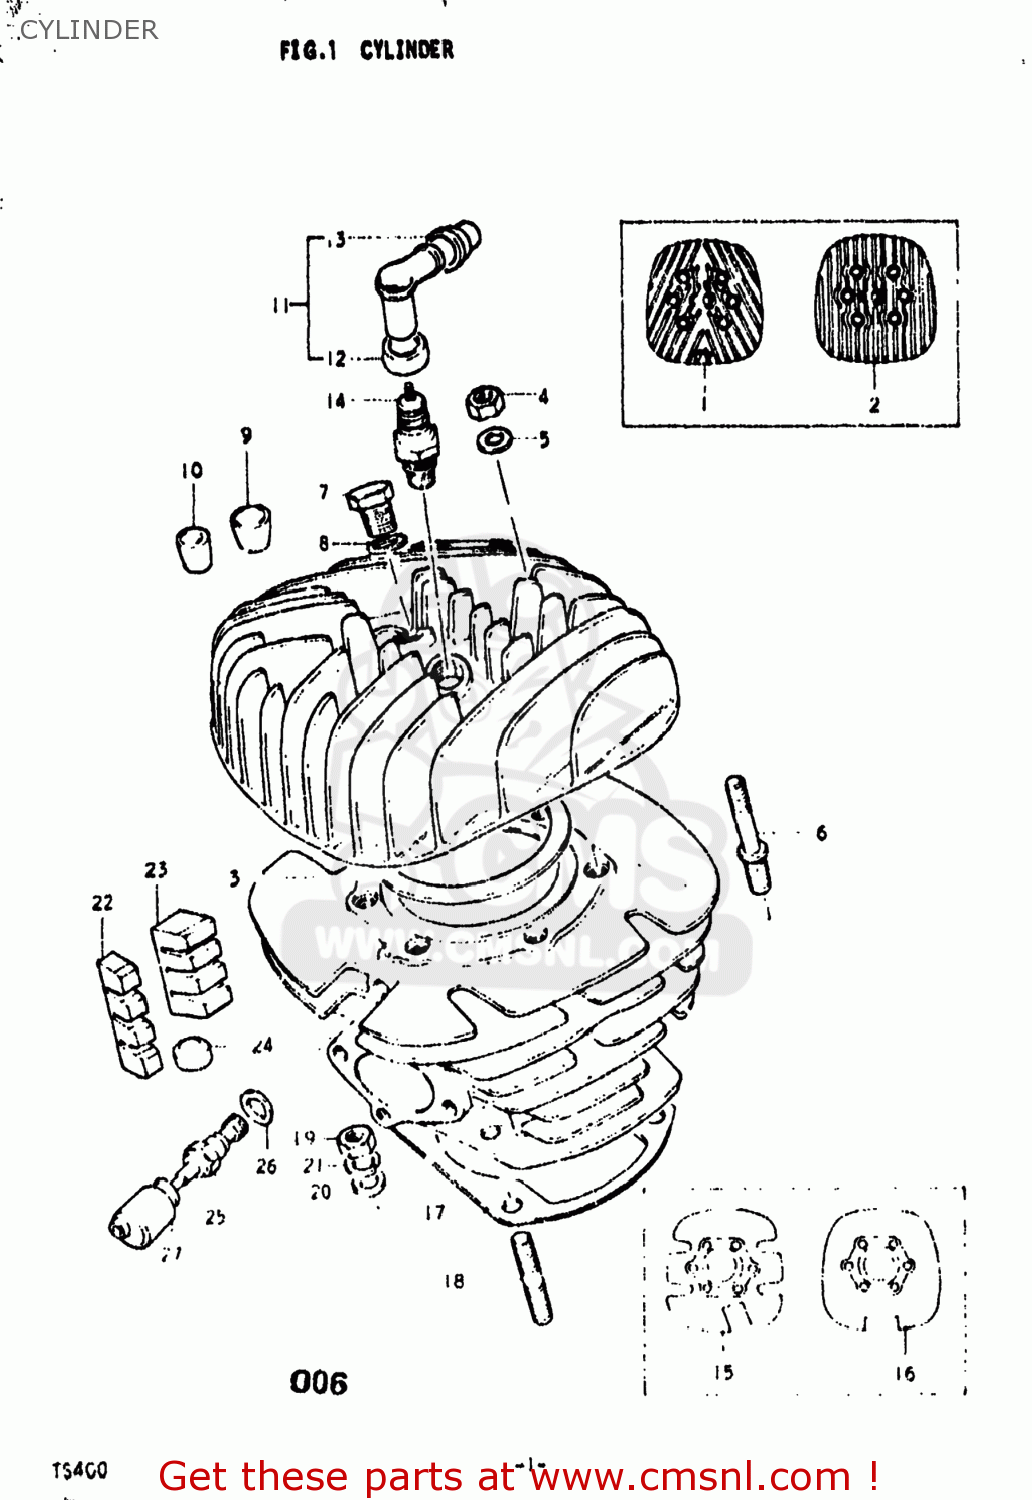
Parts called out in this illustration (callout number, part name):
1	HEAD,CYLINDER
2	HEAD,CYLINDER
3	GASKET,CYLINDER HEAD (NAS)
4	NUT (8MM)
5	WASHER
6	BOLT,STUD
7	PLUG
8	GASKET(14X19.2X2) (NAS)
9	PAD,CYLINDER HEAD
10	PAD,CYLINDER HEAD
11	CAP,SPARK PLUG
12	SEAL,SPARK PLUG
13	SEAL,SPARK PLU
14	PLUG,SPARK
15	CYLINDER
16	CYLINDER
17	GASKET,CYLINDER (MCA)
18	STUD BOLT
19	NUT
20	WASHER
21	LOCK WASHER
22	GUIDE,EXHAUST VALVE
23	PAD,CYLINDER
24	PAD,CYLINDER HEAD
26	GASKET(12X16X2) (NAS)
27	VALVE,EXHAUST
